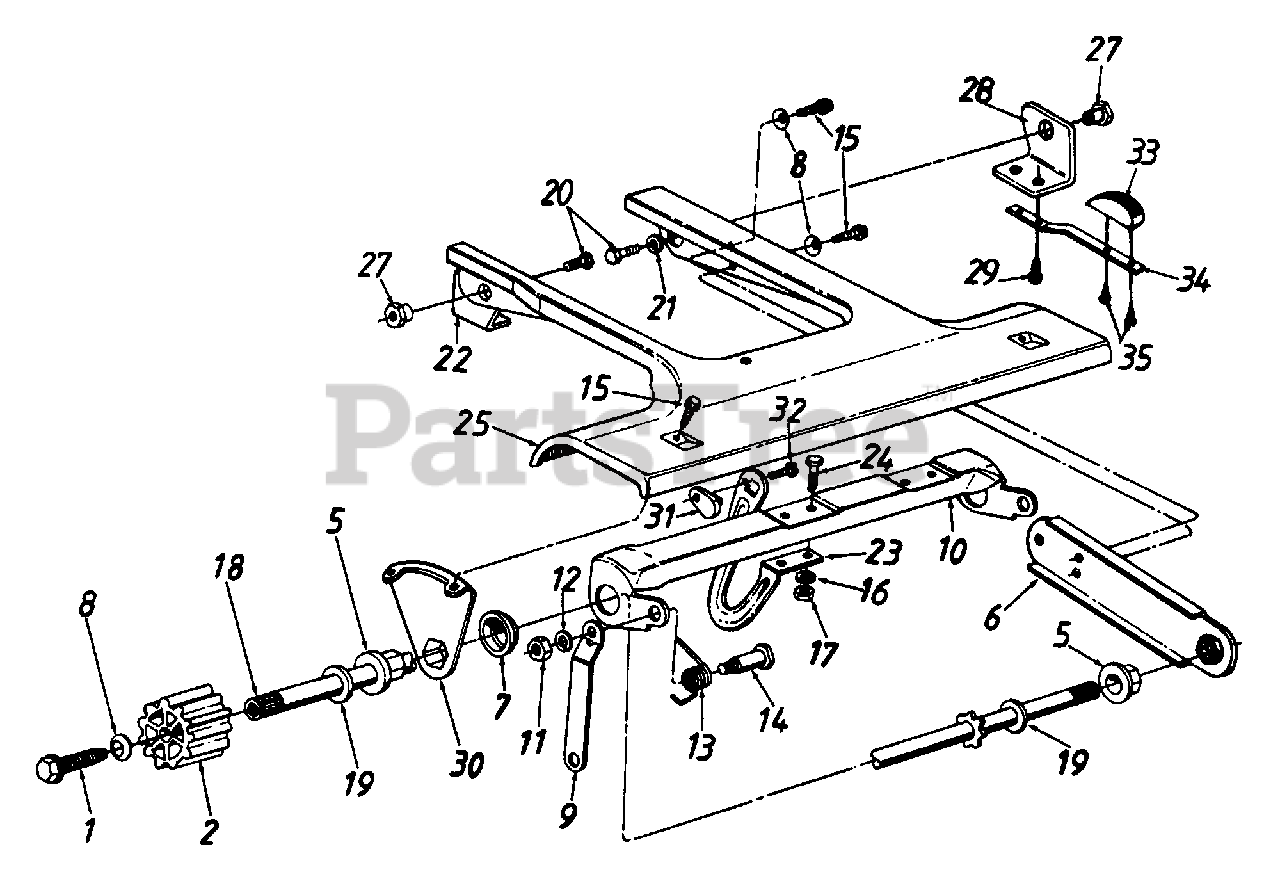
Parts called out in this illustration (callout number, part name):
1	Hex Scr. 1/4 - 20 x .75" Lg. (Gr. 5)
2	Wheel Drive Pinion
5	Hex Flange Brg. .504" I.D.
8	Bell-Wash. .265" I.D. x .75" O.D.
11	Hex Nut 5/16-18 Thd.
12	L-Wash. 5/16" I.D.
13	Torsion Spring - R.H.
14	Shoulder Bolt .437" Dia.
15	Hex Wash. Hd. AB - Tap Scr. 1/4 x .62" Lg.
16	L-Wash. 1/4" I.D.
17	Hex Nut 1/4-20 Thd.
18	Drive Shaft Ass'y.
19	Fl-Wash. .531" I.D. x .93" O.D.
20	Hex Bolt 3/8-16 x .5" Lg.
21	L-Wash. 3/8" I.D.
32	Hex B-Tap Scr. #10 x .44" Lg.
33	Chain Tensioner
34	Cantilever Spring
35	Hex Wash. B-Tap Scr. #10 x .38" Lg.
